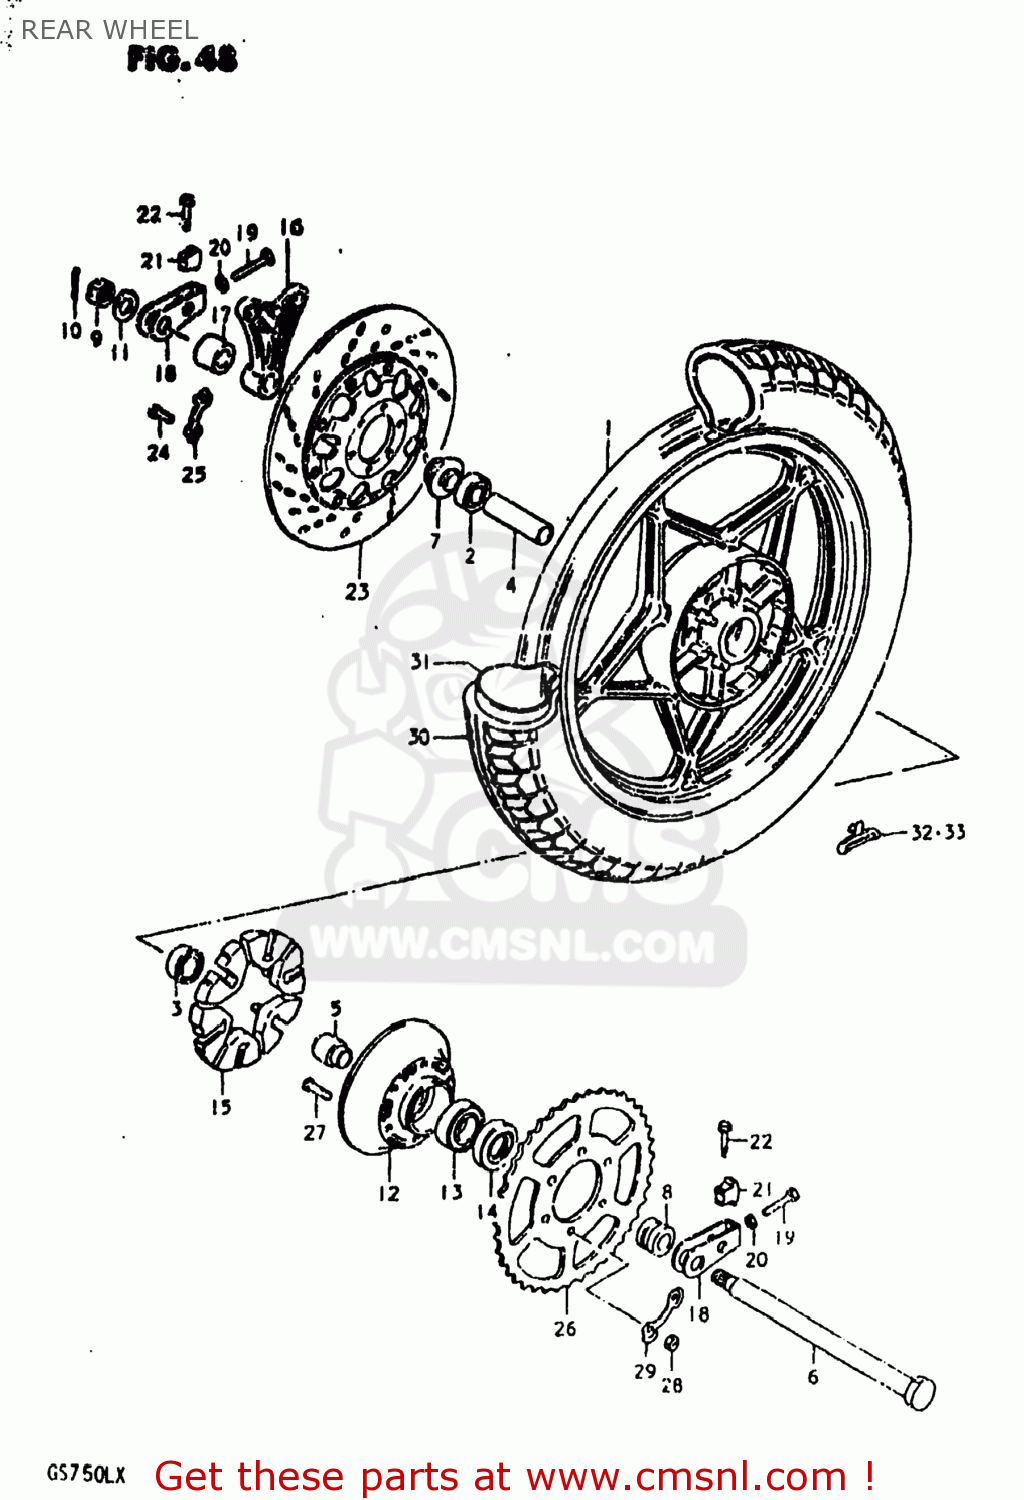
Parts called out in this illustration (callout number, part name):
1	WHEEL,REAR
2	BEARING WHEEL REAR(20X47X14)
3	BEARING, LH
4	SPACER(20.5X28X88)
5	SPACER,REAR HUB BEARING
6	AXLE,REAR
7	SPACER,REAR AXLE
8	SPACER
9	NUT 18MM
10	PIN,COTTER
11	WASHER(19X34X4)
12	DRUM,REAR SPROCKET MOUNT
13	BEARING
14	SEAL,OIL(33X62X7)
15	ABSORBER,REAR HUB SHOCK
16	BRACKET,RR,CALIPER
17	SPACER(20X38X12)
18	ADJUSTER,CHAIN
19	BOLT 8X50
20	NUT
21	SUPPORTER,CHAIN ADJUST
22	BOLT (8X40)
23	DISC,RR BRAKE
24	BOLT(8X30)
25	WASHER
26	SPROCKET,RR(NT:40)
27	BOLT
28	NUT
29	WASHER
30	TIRE
31	TUBE ASSEMBLY,WHEEL,INNER
32	BALANCER,WHEEL
33	BALANCER,WHEEL
